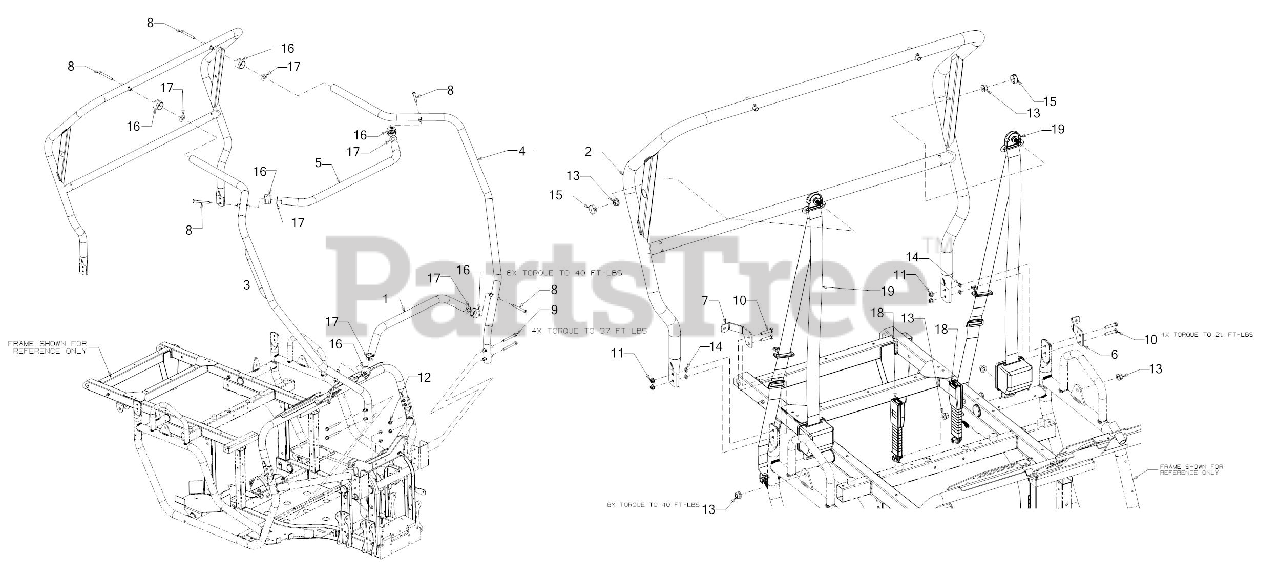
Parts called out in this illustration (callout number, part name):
1	FRONT OPS ASSEMBLY
2	REAR OPS ASSEMBLY
3	FRONT OPS ASSEMBLY (RH)
4	FRONT OPS ASSEMBLY (LH)
5	TOP CROSS BAR
6	FENDER BRACKET (LH)
7	FENDER BRACKET MOUNT (RH)
8	HEX CAP SCREW 3/8-16:3.25
9	HEX FLANGE BOLT 3/8-16:3.50
10	SCREW 5/16-18 x 1.50 GR5
11	FLANGE LOCK NUT 5/16-18
13	FLANGE LOCK NUT
15	PANEL PLUG
16	TUBE COLLAR
17	FLAT WASHER .760ID X1.49OD x .06
18	3-POINT SEAT BELT
19	3-POINT SEAT BELT
